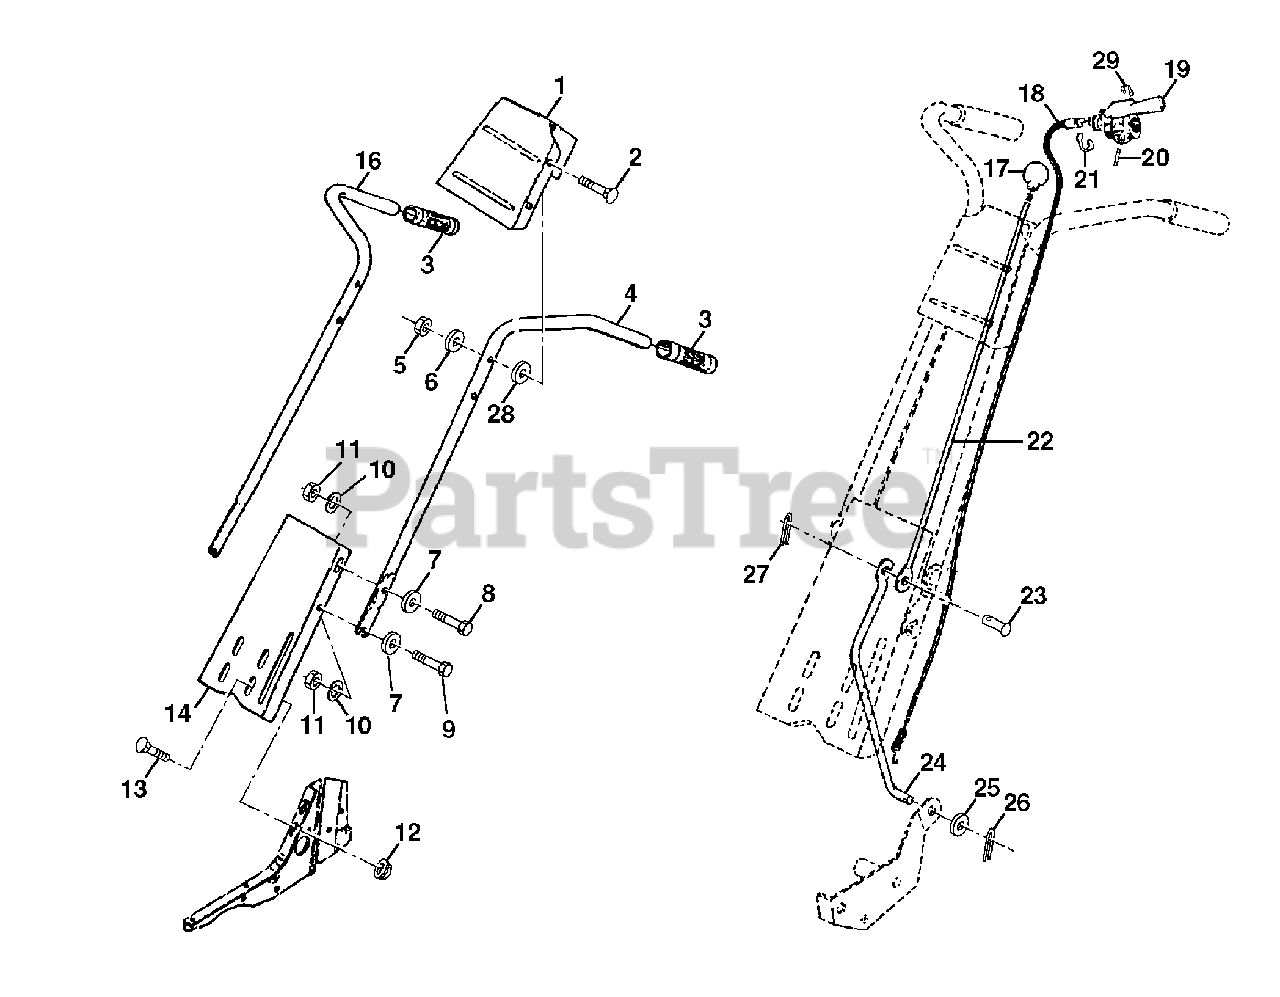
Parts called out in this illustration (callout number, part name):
1	Panel Pnt Control
2	Bolt, Carriage 5/16-18 UNC x 1-1/2
3	Grip, Handle
4	Handle, L.H.
5	Locknut, Crown 5/16-18
6	Washer 11/32 x 11/16 x 16 Ga.
7	Washer 3/8 x 7/8 x 14 Ga.
8	Bolt, Hex Hd. 5/16-18 x 1
9	Bolt, Hex Hd 5/16-18 x 3/4
10	Washer, Lock 5/16
11	Nut, Hex 5/16-18
12	Nut, Flanged 5/16-18
13	Bolt, Carriage 5/16-18 x 3/4 Gr. 5
16	Handle, R.H.
17	Knob, Control, Reverse
18	Cable, Control, Tine
19	Lever, Control, Tine
20	Pin, Pivot
21	Ring, Klip
22	Rod, Reverse, Upper
23	Pin, Retaining
24	Rod, Reverse, Lower
25	Washer 13/32 x 13/16 x 16 Ga.
26	Pin, Cotter 1/8 x 3/4
27	Pin, Cotter 3/32 x 1/2
28	Washer 13/32 x 13/16 x 12 Ga.
29	Retaining, Ring
